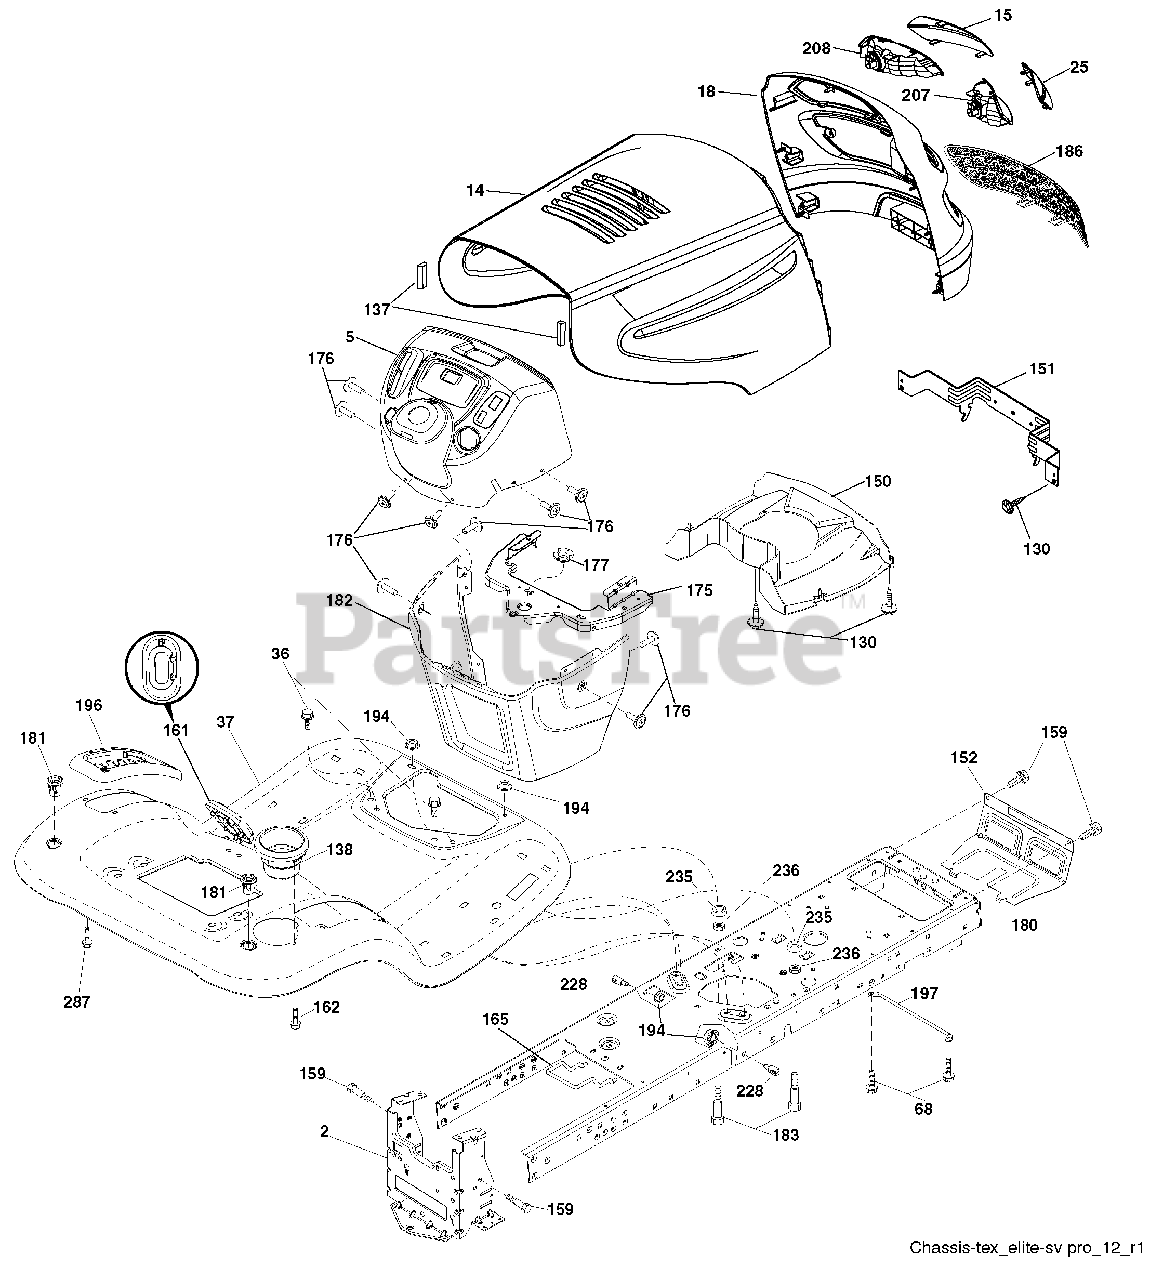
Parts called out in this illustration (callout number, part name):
2	Drawbar
14	Hood
15	Lens Grille LH
18	Grille
25	Lens Grille RH
36	Screw 5/16-18 x 3/4
37	Fender
68	Screw THDROL 5/16-18 x 1/2
130	Screw #10 x 0.750 BOS Thread
137	Bumper Hood
138	Cupholder
150	Duct Heat Hood
151	Bracket Pivot
152	Shield Browning/Debris
159	Screw Hexwsh Thdrol 3/8-16 x 3/4
161	Window Fuel
162	Screw Hex Wsh Hi-Lo 1/4 x 1/2 unc
165	Bracket Support Tank
175	Crossmember
176	Screw 10-24 x 5/8 Wshd Qdrx
177	Bushing Steering
181	Bushing Mtg. Fender Crgo.
182	Dash Lower
183	Bolt Fin Hex 5/16-18 x 1-1/4
194	Nut Lock Hex Flange 5/16-18
196	Console Asm. Deck Lift
197	Rod Pivot Chassis
207	Bezel RH
208	Bezel LH
228	Stud Fastener
235	Spacer Fender
236	Nut Center lock 5/16-18 unc
287	Screw Hex Washead 1/4-20 x 3/8
